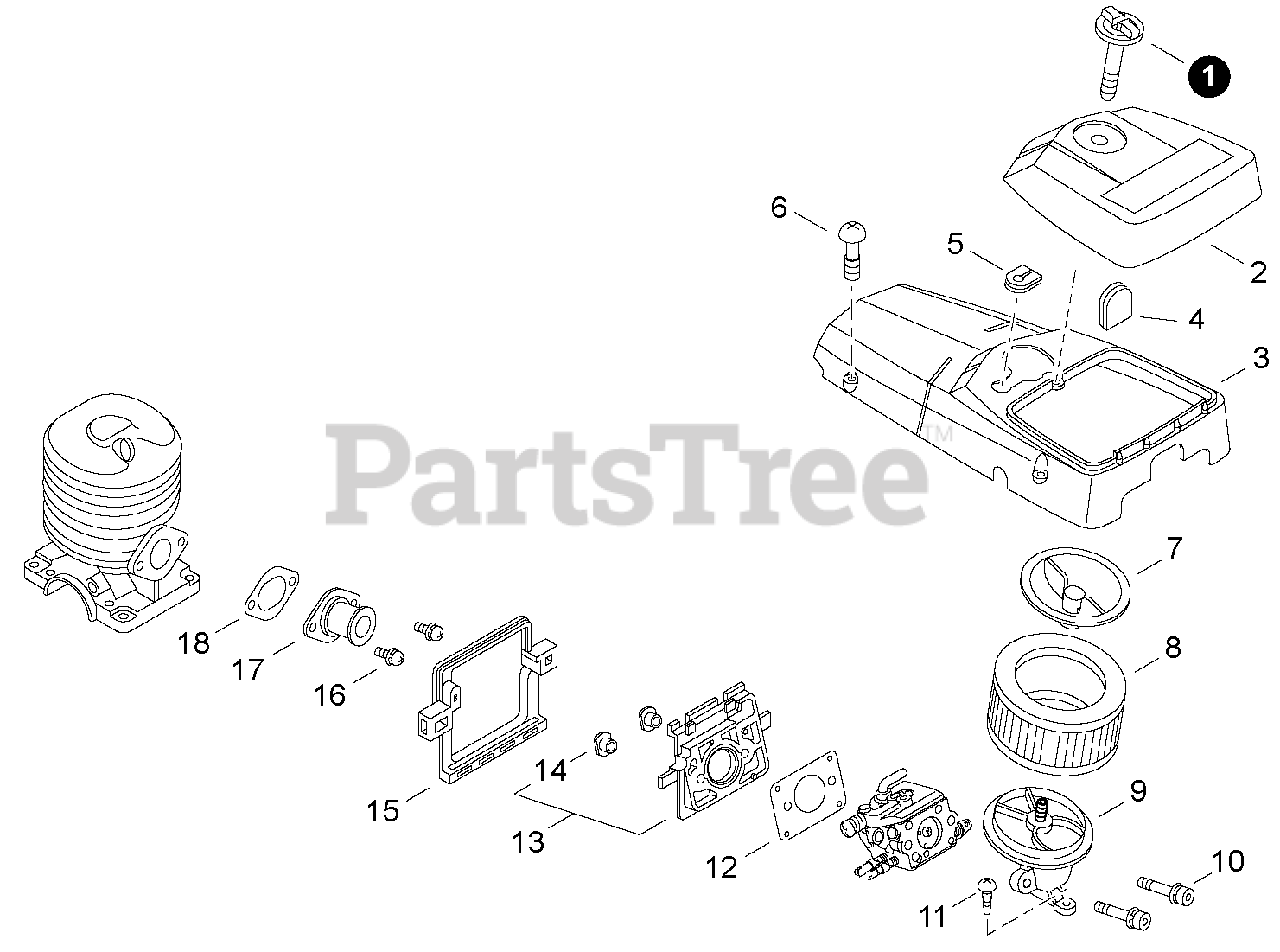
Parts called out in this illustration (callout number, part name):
1	THUMBSCREW
2	COVER, AIR FILTER
3	COVER, ENGINE
5	GROMMET
6	SCREW - 5
7	COVER, AIR FILTER
8	FILTER, AIR
9	ADAPTOR, INTAKE
10	SCREW - 5X50
11	SCREW - 5X16 -- TAPPING
12	GASKET, INTAKE
13	INSULATOR KIT
15	CUSHION
16	SCREW - 5X12
17	ADAPTOR, INTAKE
18	GASKET, INTAKE
